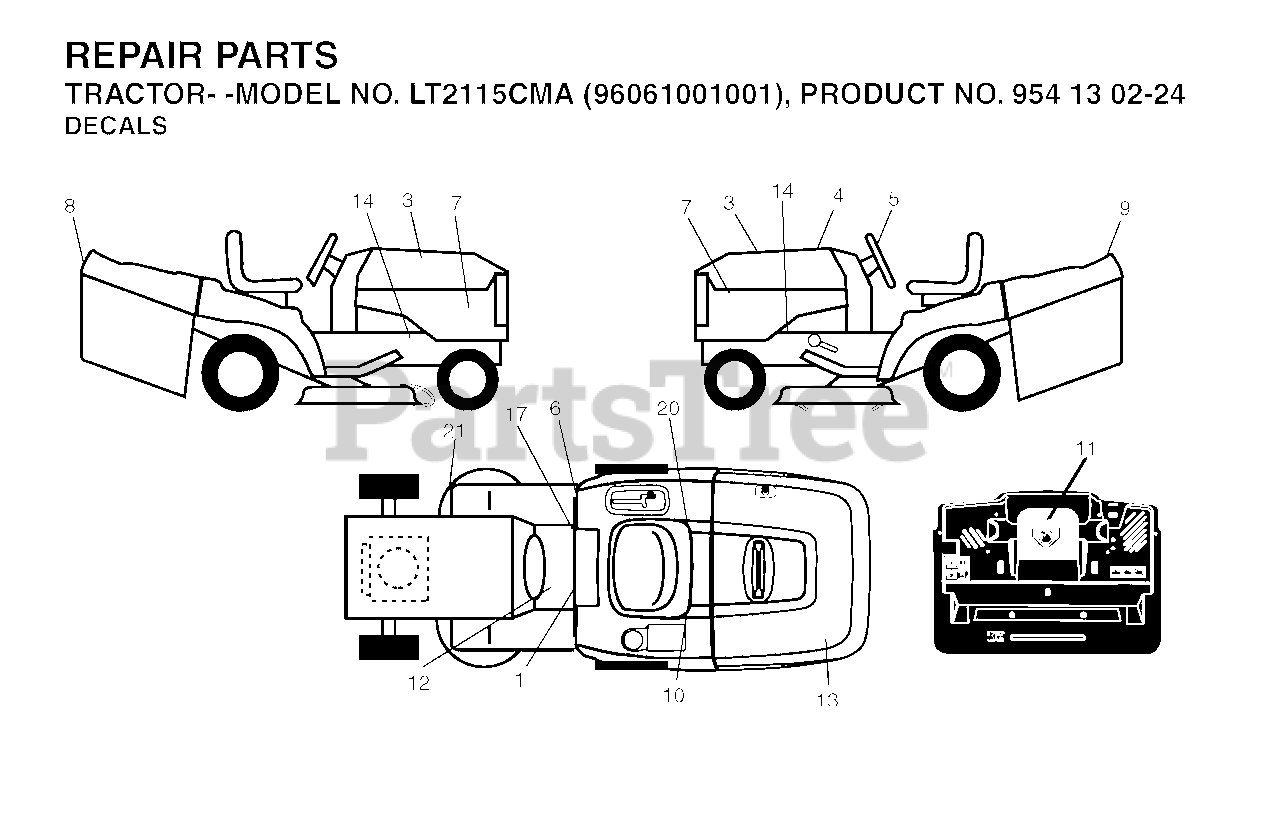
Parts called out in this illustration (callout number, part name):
1	DECAL READ OWNER'S MAN SYMS
10	DECAL BTRY SYMBOLS
11	DECAL.INTERNATIONL.CUTFINGER
17	DECAL PARK BRAKE
20	DECAL.BYPASS.FENDER.CRD.LT.YT
